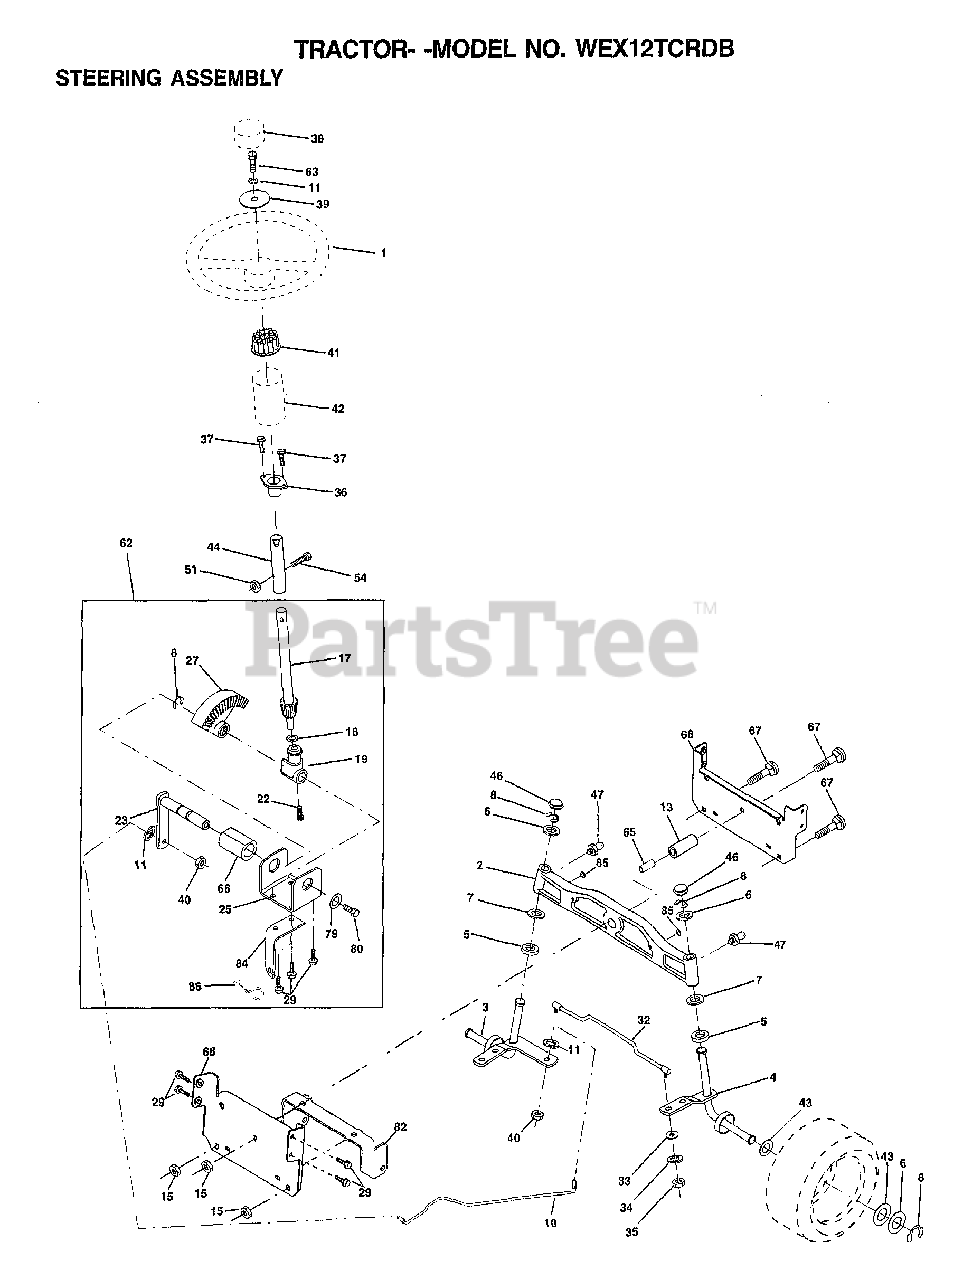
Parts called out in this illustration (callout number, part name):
1	WHEEL STR AYP BLK
2	AXLE ASSY
3	SPINDLE ASM
4	SPINDLE ASM
5	WASHER .T
6	WASHER
7	WASHER
8	RING
10	LINK DRAG
11	LOCKWASHER
13	SPACER BEARING
15	NUT.HXFLG.LOCK.
17	SHAFT ASM STEERIN
18	THRUST WASHER
19	SUPPORT.SHAFT.STEER
22	SCREW.HX.WSH.HD
23	SHAFT.ASM.PITMAN
25	BRKT-STEERING
27	GEAR SECTOR
29	SCREW
32	TIE ROD
33	WASHER M
34	LOCKWASHER
35	NUT.LOCK.5/16-24
36	BUSHING.STEERING
37	"SCREW-TT,10-32 FL"
38	CAP WHEEL STEER
39	WASHER
40	GRIPCO NUT
41	ADAPTER LT
42	BOOT.STEERING.DASH.P/L
43	WASHER
44	EXT SHAFT STEERIN
46	CAP
47	ZERK M
51	NUT
54	BOLT
62	KIT.STEER.ASM
63	BOLT
65	"SPACER BRCAE,AXLE"
66	"BEARING-ARM,PITMA"
67	BOLT RDHD 3/8-16
68	BRACE AXLE
79	WASHER
80	BOLT.HX.NYLON3/8-16X3/
82	BRKT SUSP CHASSIS FRT
84	BRACKET CABLE CLUTCH CHASSIS
85	XMAS TREE FASTNER
86	RETAINER SPRING
